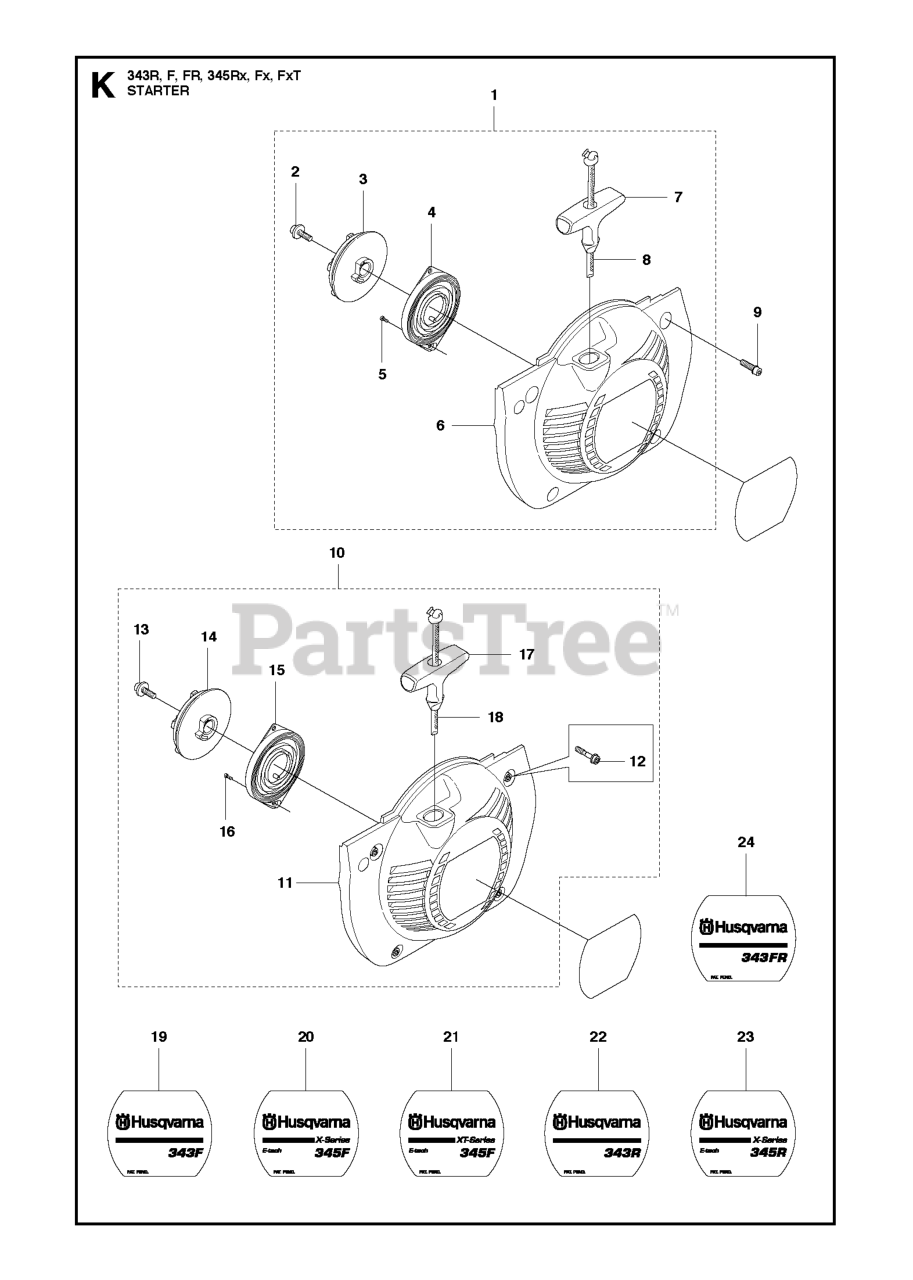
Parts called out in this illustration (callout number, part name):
1	AIR FILTER ASSY
2	AIR FILTER CLIP
4	AIR FILTER
5	FILTER HOLDER
7	SCREW ITXSCM M4X50 T20 12.9 T
9	FILTER HOLDER XP
11	SLEEVE
12	CARBURETOR HD-12B EPA WALBRO
12	CARBURETOR WALBRO HD-6B
17	PIPE
17	INTAKE PIPE - EPA
18	HOSE CLAMP
